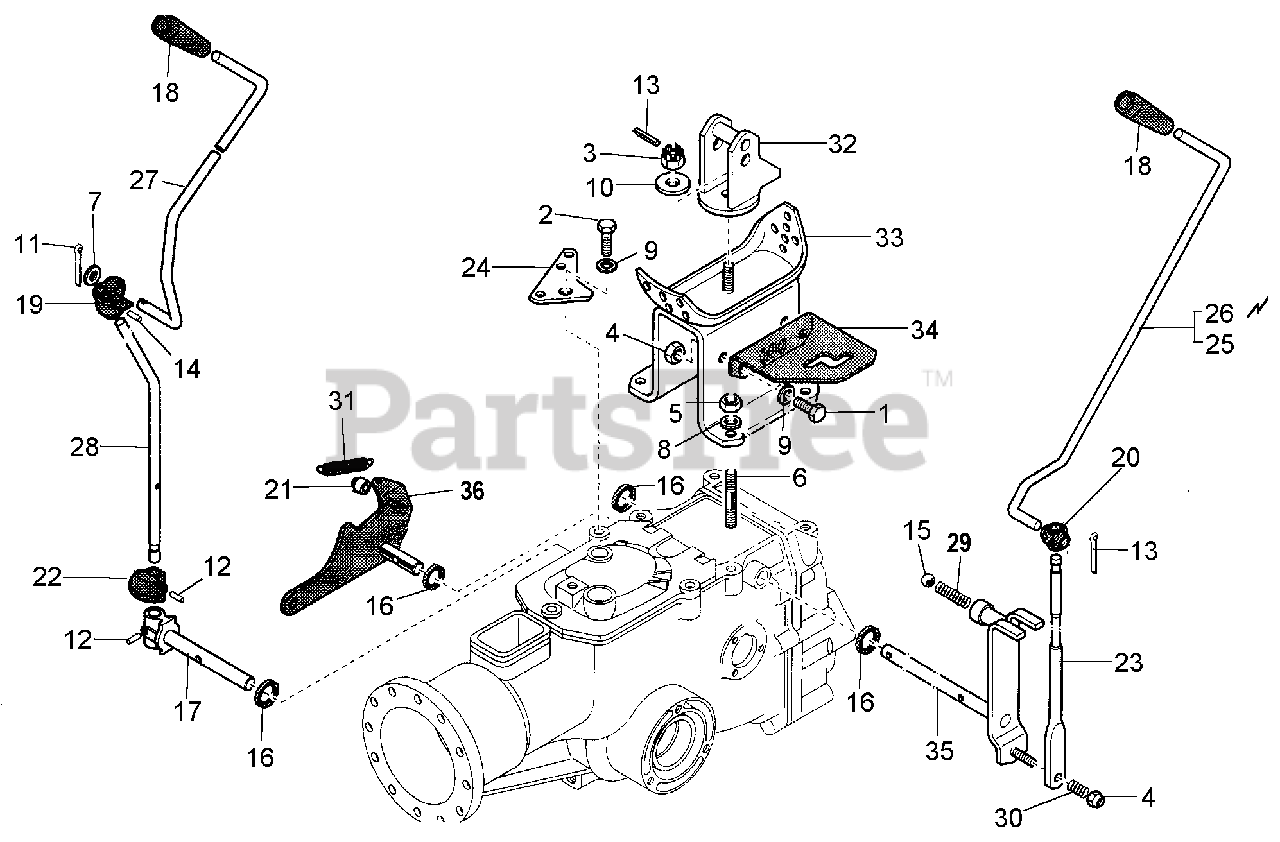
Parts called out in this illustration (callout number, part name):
1	SCREW, M8X20
2	SCREW, M8X30
3	NUT, CASTLE, M12
4	NUT, SELF LOCKING, M8
6	STUD, M8X38X14X20
7	WASHER, M10.5
8	SUPER WASHER
9	WASHER, LOCK, M8.4
10	LOCK WASHER, M13
12	PIN, LOCKING, M4X20
13	PIN, LOCKING, M3X22
14	PIN, LOCKING, M4X24
15	BALL, 15/32"
16	OIL SEAL, 14X22X4
19	PTO ARTICULATION
20	SPEED ARTICULATION, 716, 720, 730
21	PTO LOCKOUT RING
22	PTO STOP RING
23	SPEED CONTROL LEVER
24	REVERSE BRACKET
25	SPEED CONTROL ROD, RECOIL START
26	SPEED CONTROL ROD, ELECTRIC START
27	PTO CONTROL ROD, ELECTRIC START
28	PTO CONTROL LEVER
32	HANDLE BAR SUPPORT
33	HANDLE BAR ANCHOR
34	GEAR SELECTOR, 716, 720, 730
35	SPEED CONTROL LEVER, 716, 720, 730
36	REVERSE LEVER
